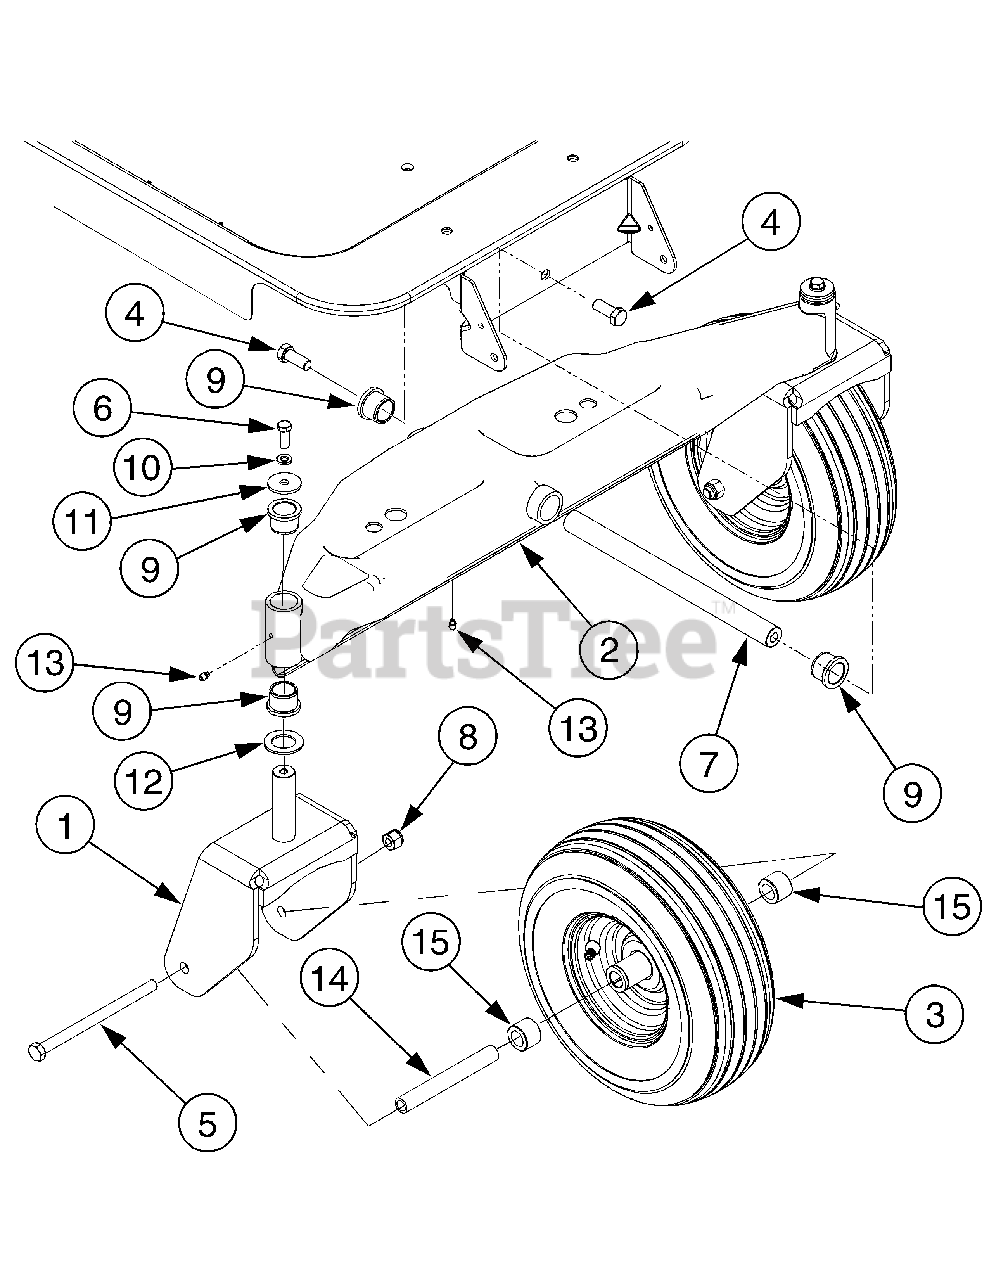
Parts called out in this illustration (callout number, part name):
4	Screw, Hex Lock, 1/2-13 x 1.25 GR5
5	Screw, Hex Cap, 1/2-20 x 7.25 Gr5
6	Screw, Hex Cap, 3/8-16 x 1.0 GR5
7	Shaft, Axle
8	Nut, Hex Insert Lock, 1/2-13 GRB
9	Bearing, Flange, 1.0 x 1.246
10	Washer, Lock, 3/8
11	Washer, Flat, .39 x 1.5 x .134
12	Washer, Flat, 1.0 x 1.75 x .10
13	Fitting, Lube, 3/16 Drive
14	Spacer, .51 x .75 x 5.825
15	Hub, .76 x 1.23 x .92
